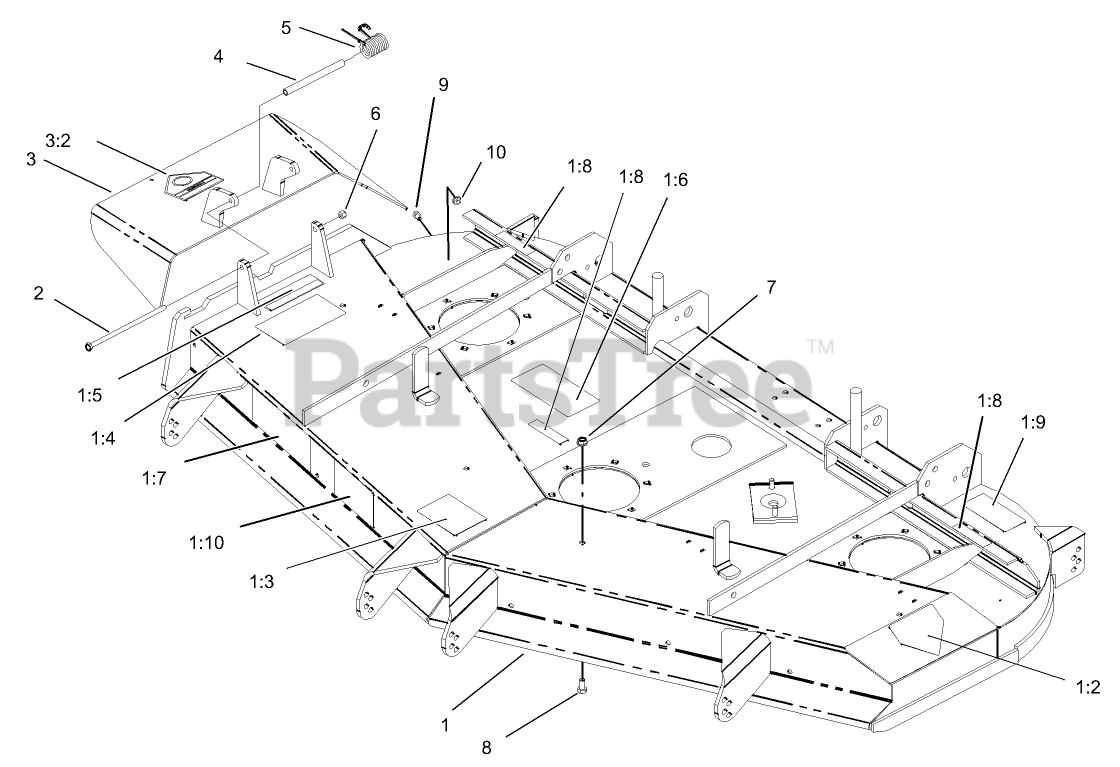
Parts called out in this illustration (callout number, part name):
1	Deck ASM
1:2	DECAL-DANGER
1:3	DECAL-WHEEL, GAGE
1:4	DECAL-DANGER, THROWN OBJECT
1:5	DECAL-WARNING
1:6	DECAL-ROUTING, BELT
1:7	DECAL-SFS
1:8	DECAL-COVER, MISSING
1:9	DECAL-TORQUE, BLADE BOLT
1:10	DECAL-DECK
2	SCREW-HH
3	Deflector ASM
3:2	DECAL-DANGER
4	SPACER
5	SPRING-TORSION
6	NUT-LOCK, NI
7	NUT-HHF, WHIZ
8	SCREW-HH
9	SCREW-HH
10	NUT-HF
